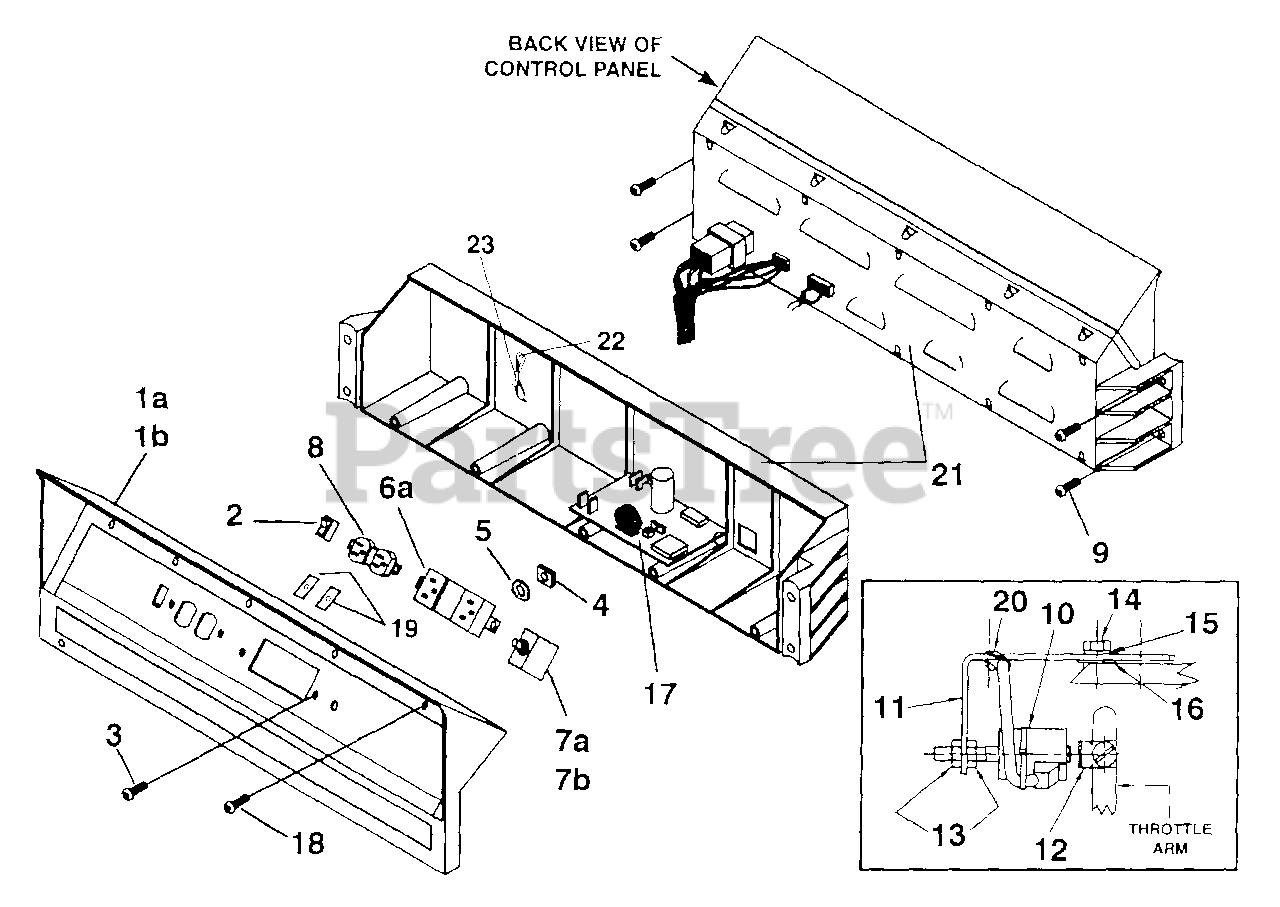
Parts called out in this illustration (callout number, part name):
1A	CONTROL PANEL (LRI2500)
1B	CONTROL PANEL (LRI2500/CSA)
2	SWITCH
3	SCREW-Pan Hd. (8-32 X 7/8")
4	NUT-Hex
5	WASHER-Lock
6A	RECEPTACLE (GFCI) (LRI2500)
7A	CIRCUIT BREAKER (20 amp) (LRI2500)
7B	CIRCUIT BREAKER (15 amp) (LRI2500/CSA)
8	RECEPTACLE-Duplex (LRI2500) (120V)
9	SCREW-Torx Hd. (10-24 X 1/2")
10	ELECTROMAGNET
11	BRACKET (5HP)
12	PADDLE (5HP)
13	NUT-Hex (1/4-28)
14	SCREW-Hex Hd. (1/4-20 X 5/8")
15	WASHER-Lock
16	WASHER-Flat
17	CONTROL BOARD
18	SCREW-Thread Forming (8-16 X 3/4")
19	BUMPER-Rubber
20	TIE-Cable
21	CONTROL PANEL-Back
22	TIE, Cable
23	Clip, Tie
